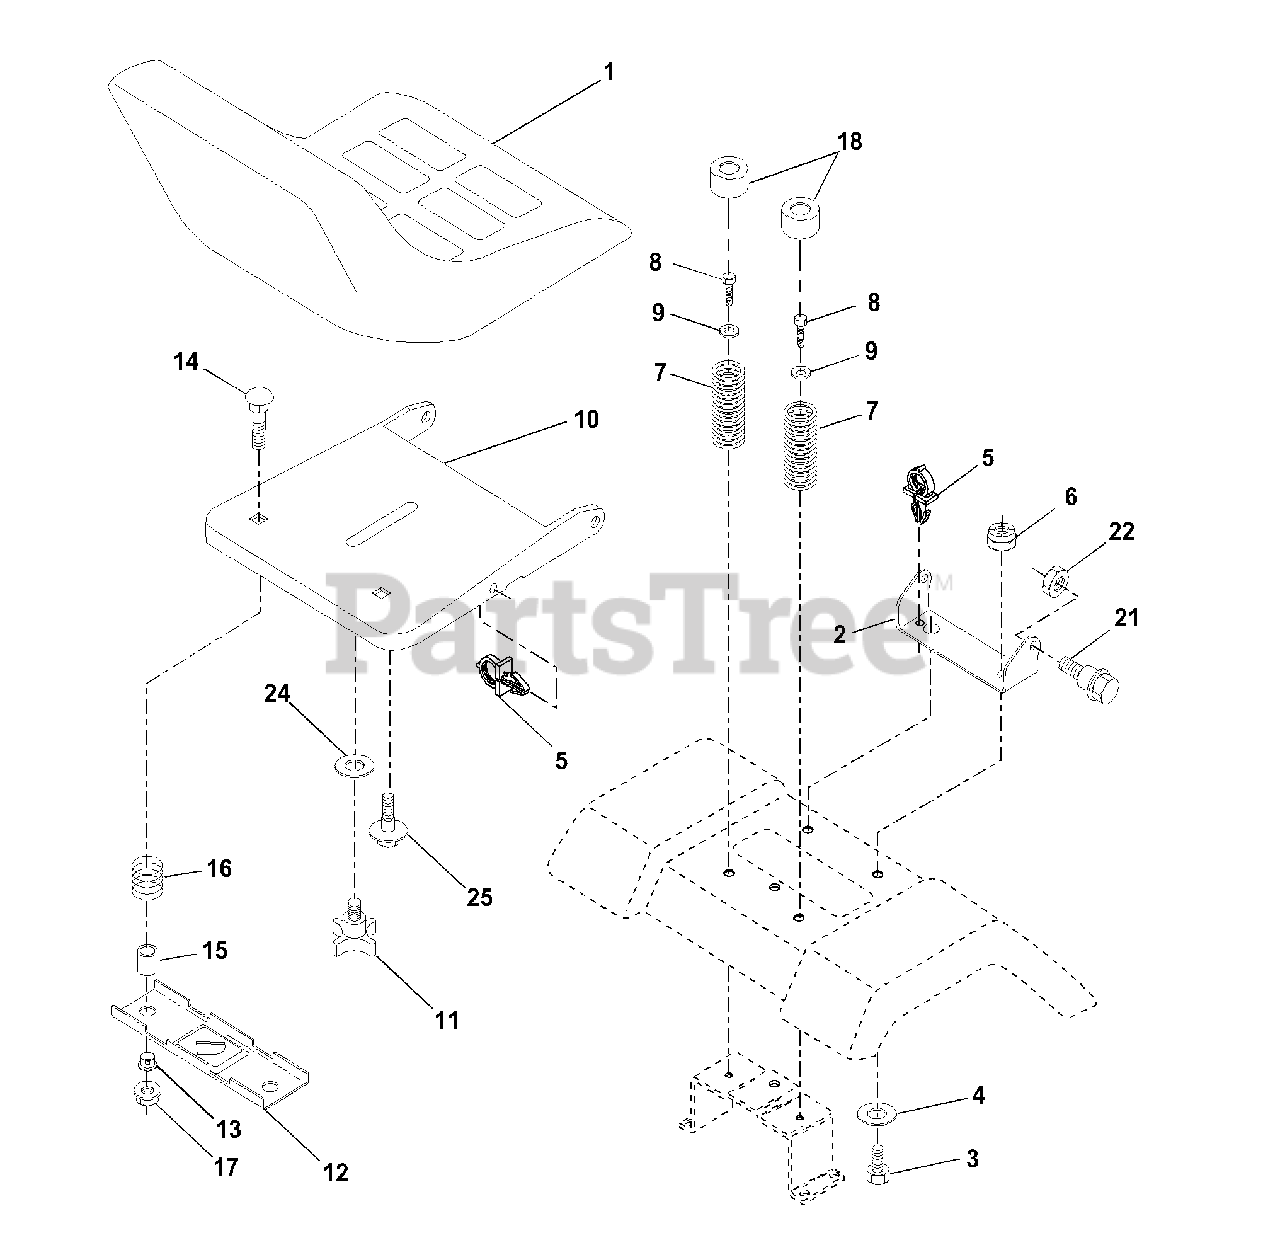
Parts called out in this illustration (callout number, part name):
1	Seat V250 Blk/blk Std
2	Bracket Pivot Seat 8 720
3	Bolt Fin Hex 3/8-16unc X 1
4	Washer 13/32 X 1 X 10 Ga
5	Clip Push-In
6	Nut Hex w/Ins. 3/8-16 Unc
7	Spring Seat Cprsn 2 250 Blk Zi
8	Screw Thdrol 3/8-16 X 1 Ty-tt
9	Washer 13/32 X 1 X 14 Ga.
10	Pan Seat
11	Knob seat 1/2-13 Unc
12	Bracket Mounting Switch
13	Bushing Snap Blk Nyl 50 Id
14	Bolt Rdhd Sht Nk 1/4-20x1-3/8
15	Spacer Split 28x 96 Yel Zinc
16	Spring Cprsn 1 27 Blk Pnt
17	Nut Lock 1/4 Lge Flg Gr 5 Zinc
18	Cap Spring Seat
21	Bolt Shoulder 5/16-18 Unc-2A
22	Nut Hex Lock W/Ins 5/16-18
24	Washer 17/32 X 1-3/16 X 12 Ga.
25	Bolt Shoulder 5/16-18 X 62
